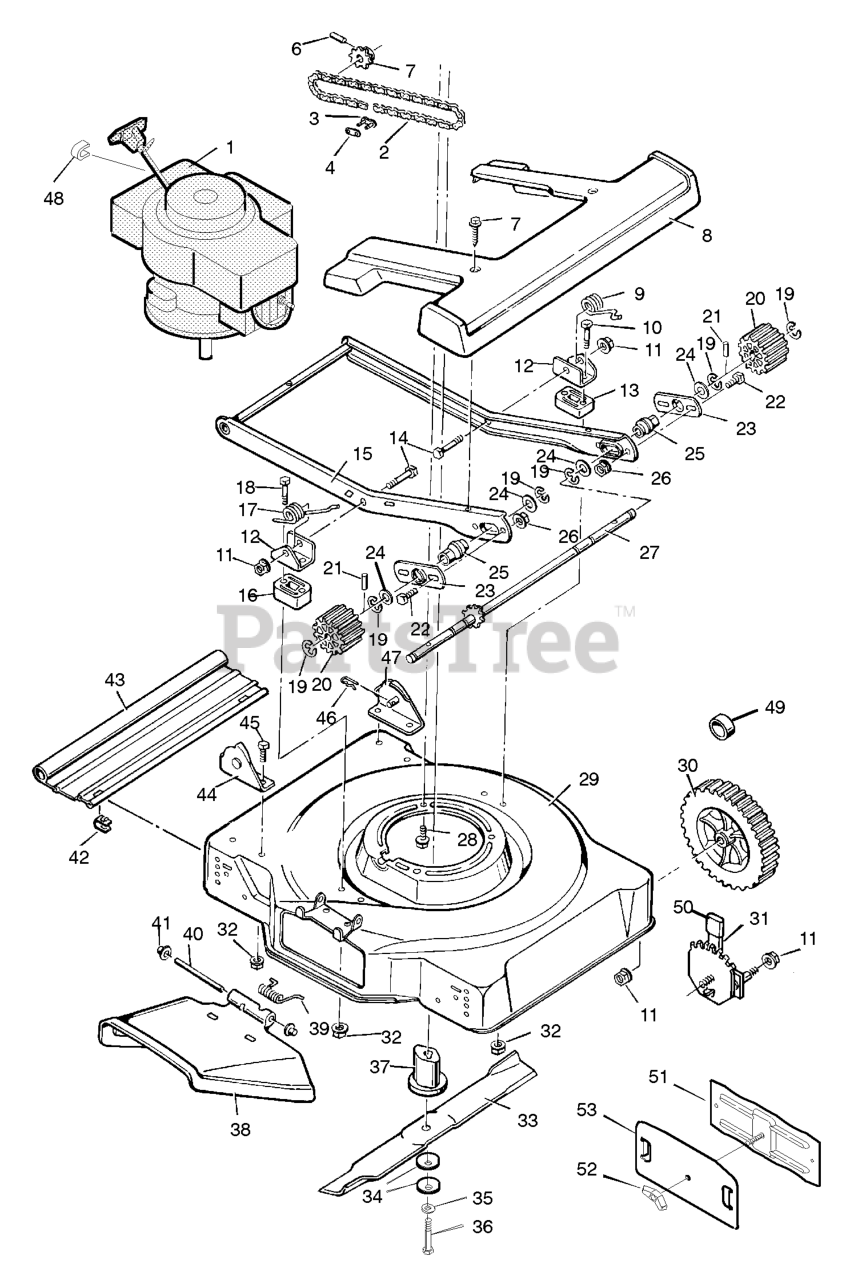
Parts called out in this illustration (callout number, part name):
1	Engine *
3	Master Link
5	Sprocket, Drive
6	Pin, Spring
7	Screw, Tapping
8	Guard, Pinion
9	Spring, Left Torsion
10	Bolt, Hex
11	Locknut, Flange
12	Bracket, Drive Arm
13	Spacer, Left
14	Bolt, Hex
15	Drive Arm Assembly
16	Spacer, Right
17	Spring, Right Torsion
18	Bolt, Hex
19	Retainer Ring
20	Drive Pinion
21	Spring Pin
22	Bolt, Hex
23	Retainer, Bearing
25	Bearing
26	Locknut, Flange
27	Drive Shaft & Sprocket
28	Bolt, Engine
29	Housing
30	WHEEL & TIRE ASSEMBLY, White, 8"
31	Height Adjuster
32	Locknut, Flange
34	Washer, Belleville
37	Blade Adapter
38	Chute Deflector
39	Spring, Torsion
40	Pin, Pivot
41	Push On Cap
42	Retainer
43	Deflector, Rear
44	Bracket, Right Handle
46	Pin, Hair
47	Bracket, Left Handle
48	Stop, Rope
49	Hub Cap
51	Baffle Assembly
52	Wingnut
53	Cover
